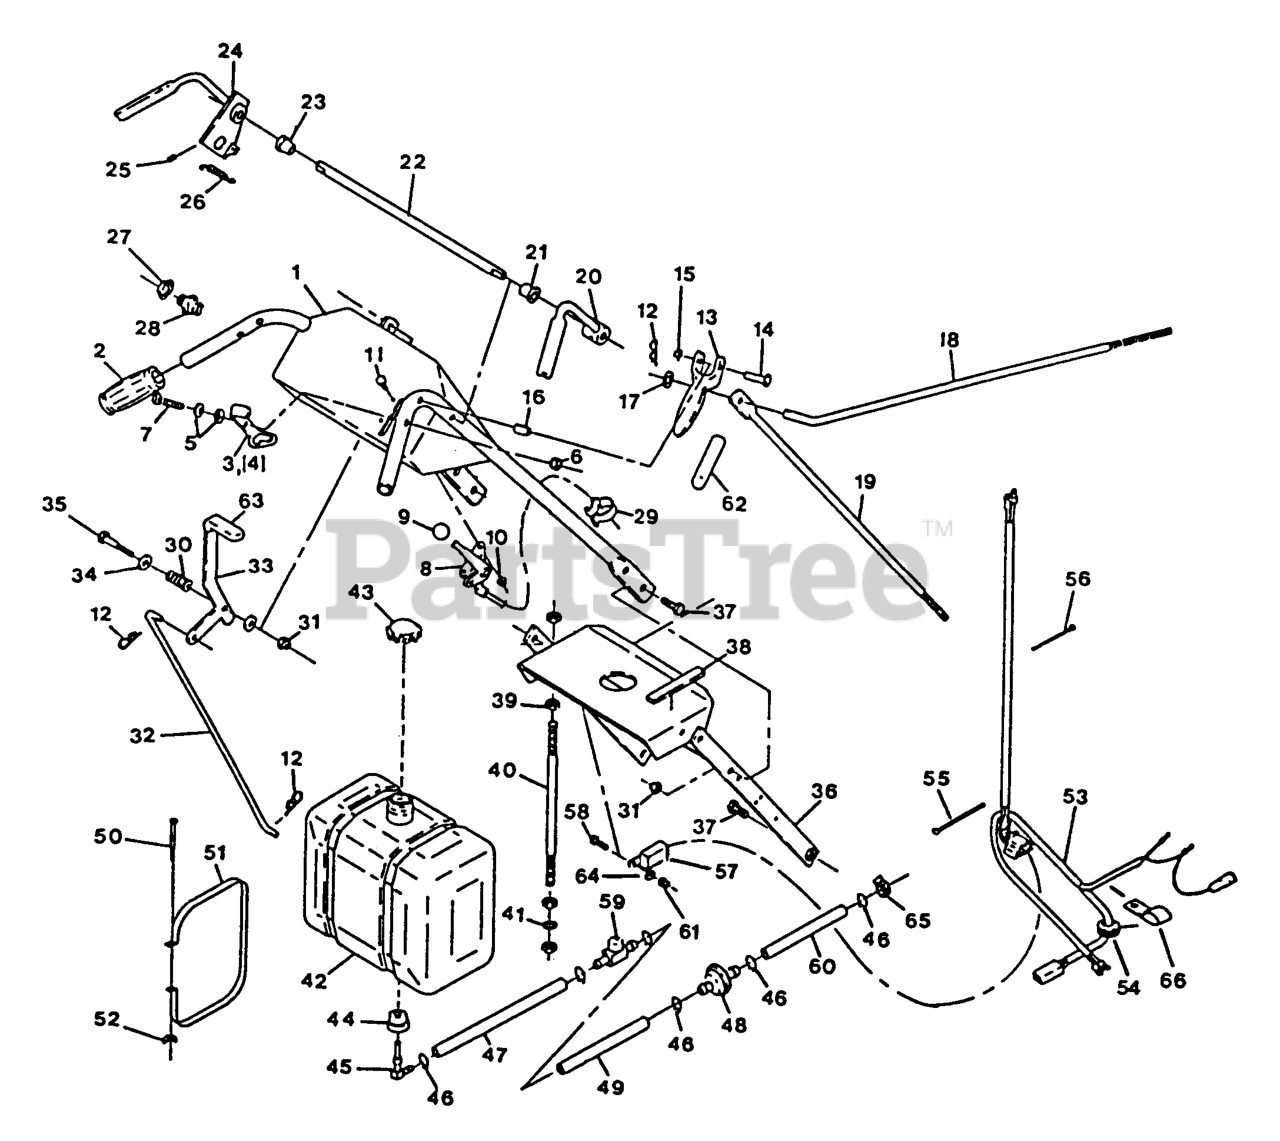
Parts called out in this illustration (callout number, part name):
3	LATCH,W/GRIP RH
4	LATCH,W/GRIP LH
5	WASHER-SPRING
8	CABLE,THROTTLE CONTROL
9	KNOB-BALL
11	BOLT-CARR
12	PIN-COTTER
13	DRIVE LEVER ASM
14	PIN-LEVER, DRIVE
15	NUT-PUSH
16	PIN-ROLL
18	LINKAGE,BRAKE
19	LINKAGE,CALIPER
21	BUSHING-NYLON
22	ROD,CONNECTING
23	BUSHING,FLANGED
25	SCREW-SET
26	SPRING-EXTENSION
28	SWITCH,OPERATOR CNTRL
29	CLIP-CABLE
30	SPRING-COMPRESSION
32	LINKAGE-BLADE, UPPER
38	PAD,PLASTIC TANK
43	CAP-FUEL
45	ELBOW-TANK, FUEL
46	CLAMP
47	FUEL LINE
50	SCRW,MACH CRPH
52	WINGNUT
53	HARNESS,WIRING KAW
54	GROMMET
55	TIE-PLASTIC
56	TIE-CABLE
57	MODULE-INTERLOCK
59	VALVE-FUEL
62	GRIP-LEVER, DRIVE
63	GRIP-LEVER
65	CLAMP-HOSE
66	CLIP-LOOM
